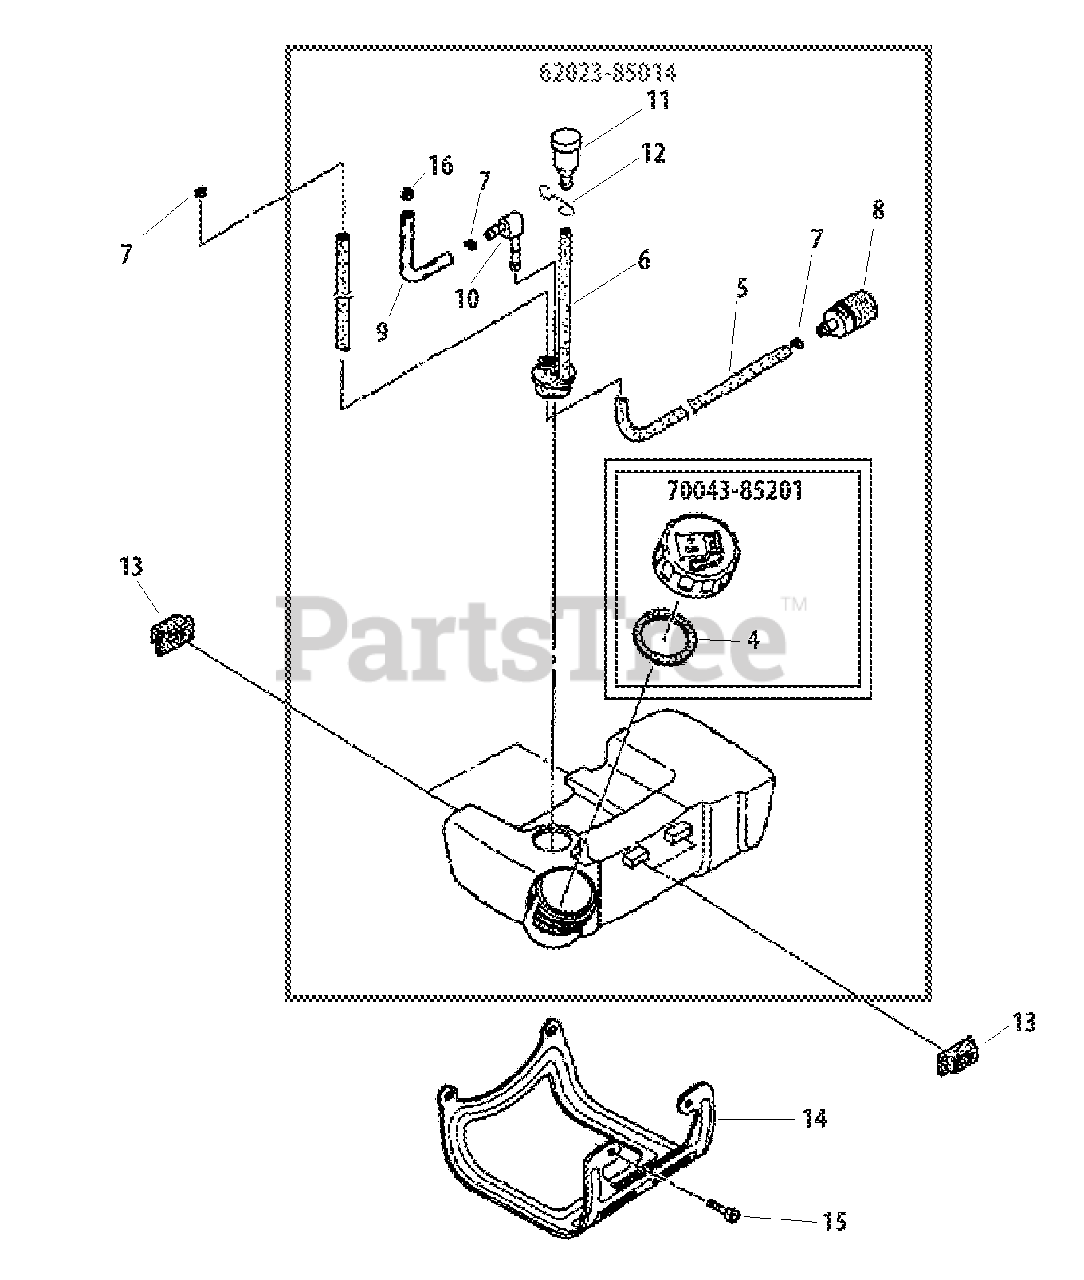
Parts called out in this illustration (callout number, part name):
4	GASKET, CAP
5	PIPE - FUEL
6	VENT PIPE ASSY
7	RING, RETAINING - 6
8	FILTER, FUEL
9	PIPE - RETURN
10	CONNECTOR, PIPE
11	VENT, FUEL TANK
12	HOLDER, VENT
13	CUSHION, TANK
14	GUARD, FUEL TANK
15	SCREW - 5X12
16	CLIP - SPRING
62023-85014	FUEL TANK ASSY
70043-85201	CAP ASSY
